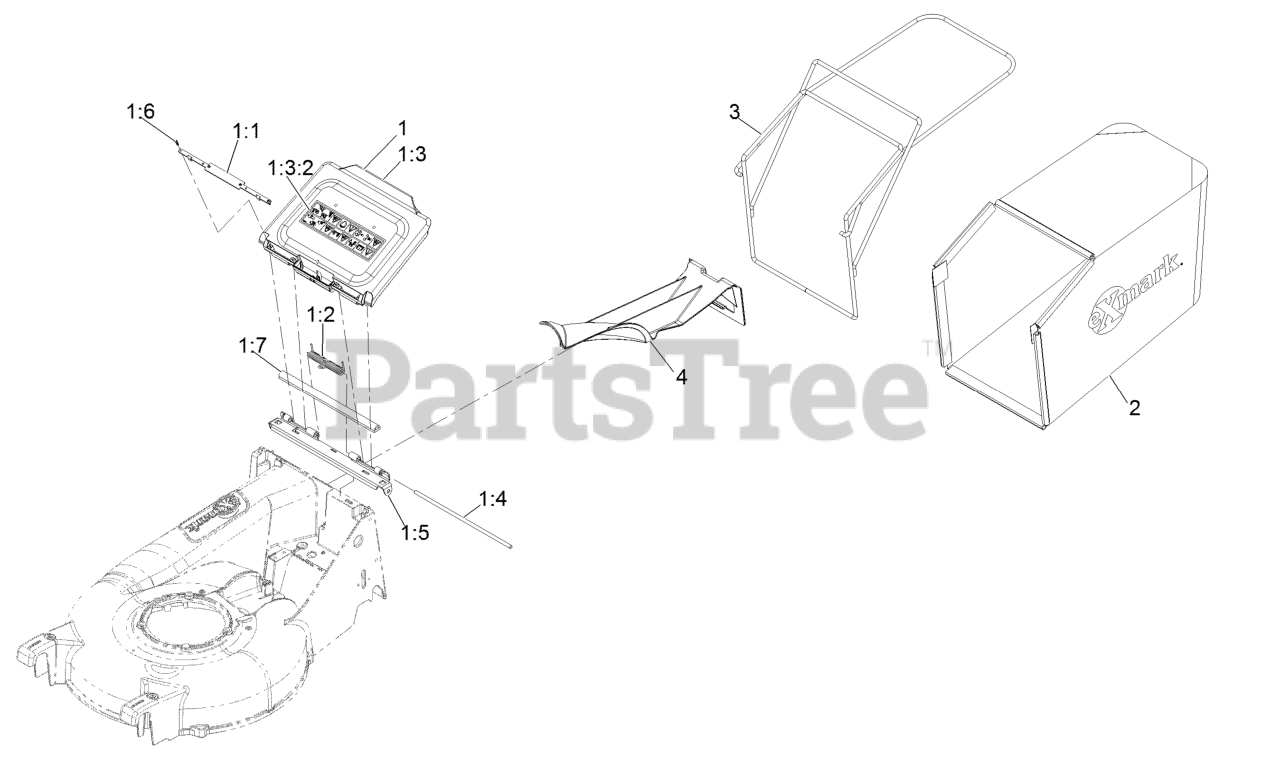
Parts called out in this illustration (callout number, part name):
1	Door ASM
1:1	Plate, Door Cover
1:2	Spring-Plastic Door
1:3	ASM-Door & Decal
1:3:2	Decal-Warning
1:4	Pin-Door Pivot
1:5	Bracket-Door Pivot
1:6	Scr,TAP,6-19X7/16,Phph,Stl, Rohs
1:7	Seal-Epdm Foam Bulb
2	Bag-21 Grass
3	Wld-Bag Frame
4	Plug,Mulch
